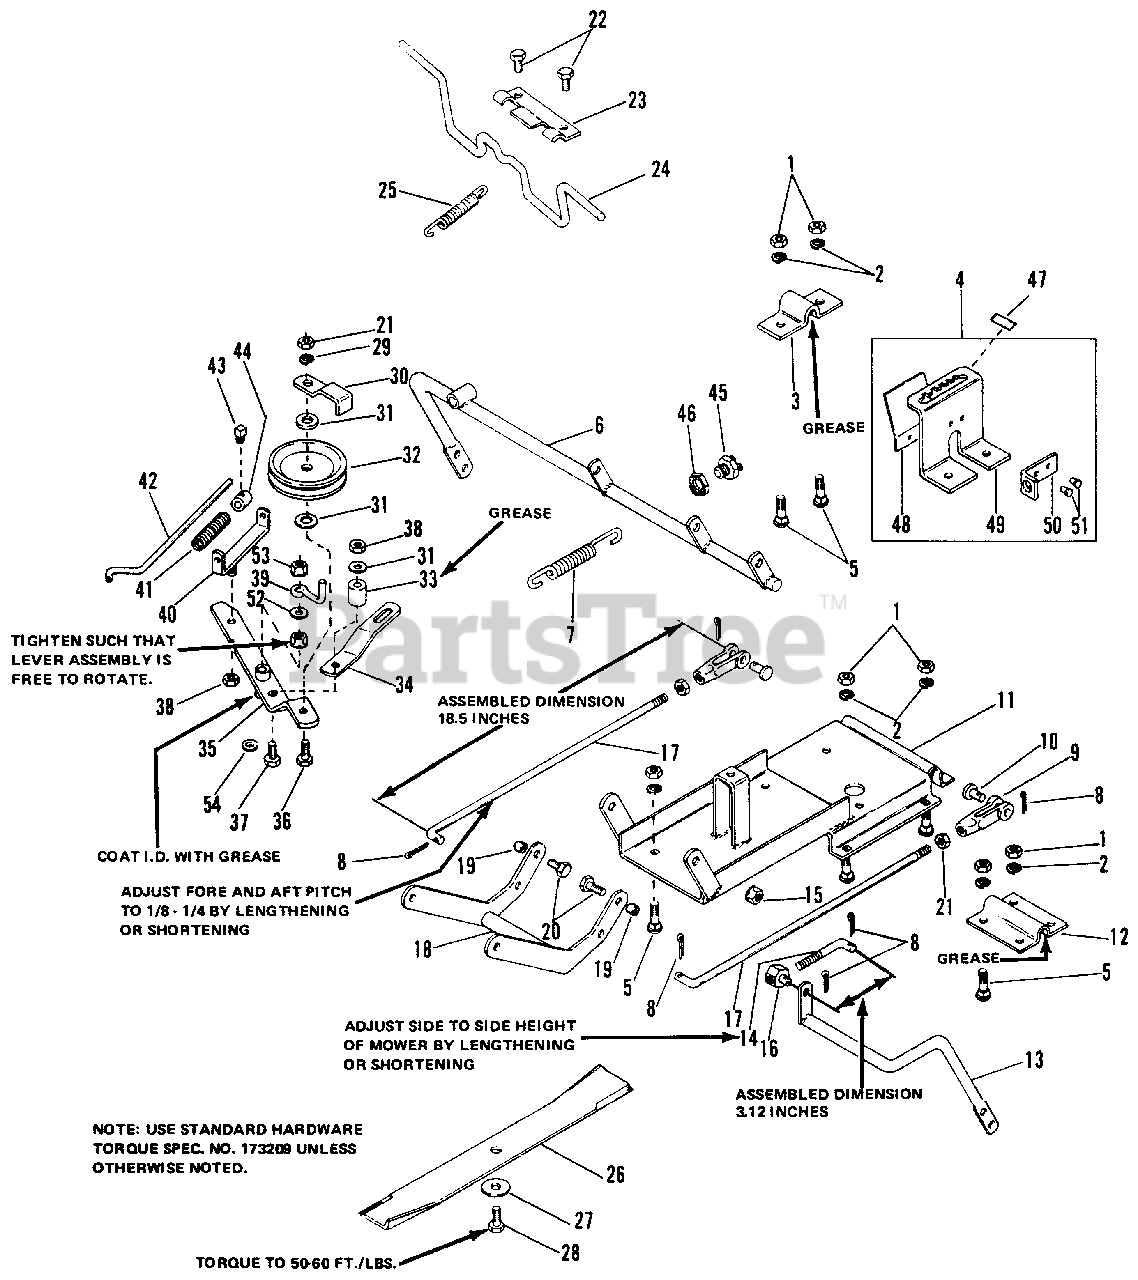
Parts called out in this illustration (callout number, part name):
1	NUT, Hex, 5/16-18
2	LOCKWASHER, 5/16
4	QUADRANT ASSEMBLY
5	BOLT, Carriage, 5/16-18 x 3/4
6	R.H. ROLLER & WHEEL SUPPORT
8	PIN, Cotter, 3/32 x 3/4
9	CLEVIS, Adjusting
10	PIN, Yoke, 3/8
11	SUPPORT ASSEMBLY
12	CLAMP, Wheel Support
13	H. ROLLER & WHEEL SUPPORT
15	NUT, Flange, 3/8-16
17	ROD, Height adjusting
18	ROCKER ARM ASSEMBLY
20	CAPSCREW, 3/8-16 x 1
21	NUT, Hex, 3/8-16
22	SCREW, Taptite, 1/4-20 x 3/8
23	SUPPORT, Brake
26	BLADE
27	WASHER, Spring
28	CAPSCREW, 1/2-20 x 1-1/4
29	LOCKWASHER, 3/8
30	GUIDE, Belt
31	WASHER, Plain, 5/16
32	PULLEY, Idler
34	LEVER, Brake
35	CLUTCH LEVER ASSEMBLY
36	CAPSCREW, 3/8-16 x 1-1/2
37	CAPSCREW, 5/16-18 x 1
38	NUT, Lock, 5/16-18
40	ROD GUIDE ASSEMBLY
42	ROD, Clutch
43	SETSCREW, Sq. Hd., 1/4-20 x 3/8
44	COLLAR, Set
46	NUT, Pal
47	DECAL, Height
50	BRACKET, Switch
52	WASHER, Plain, 3/8
53	NUT, Flange, 7/16-14
